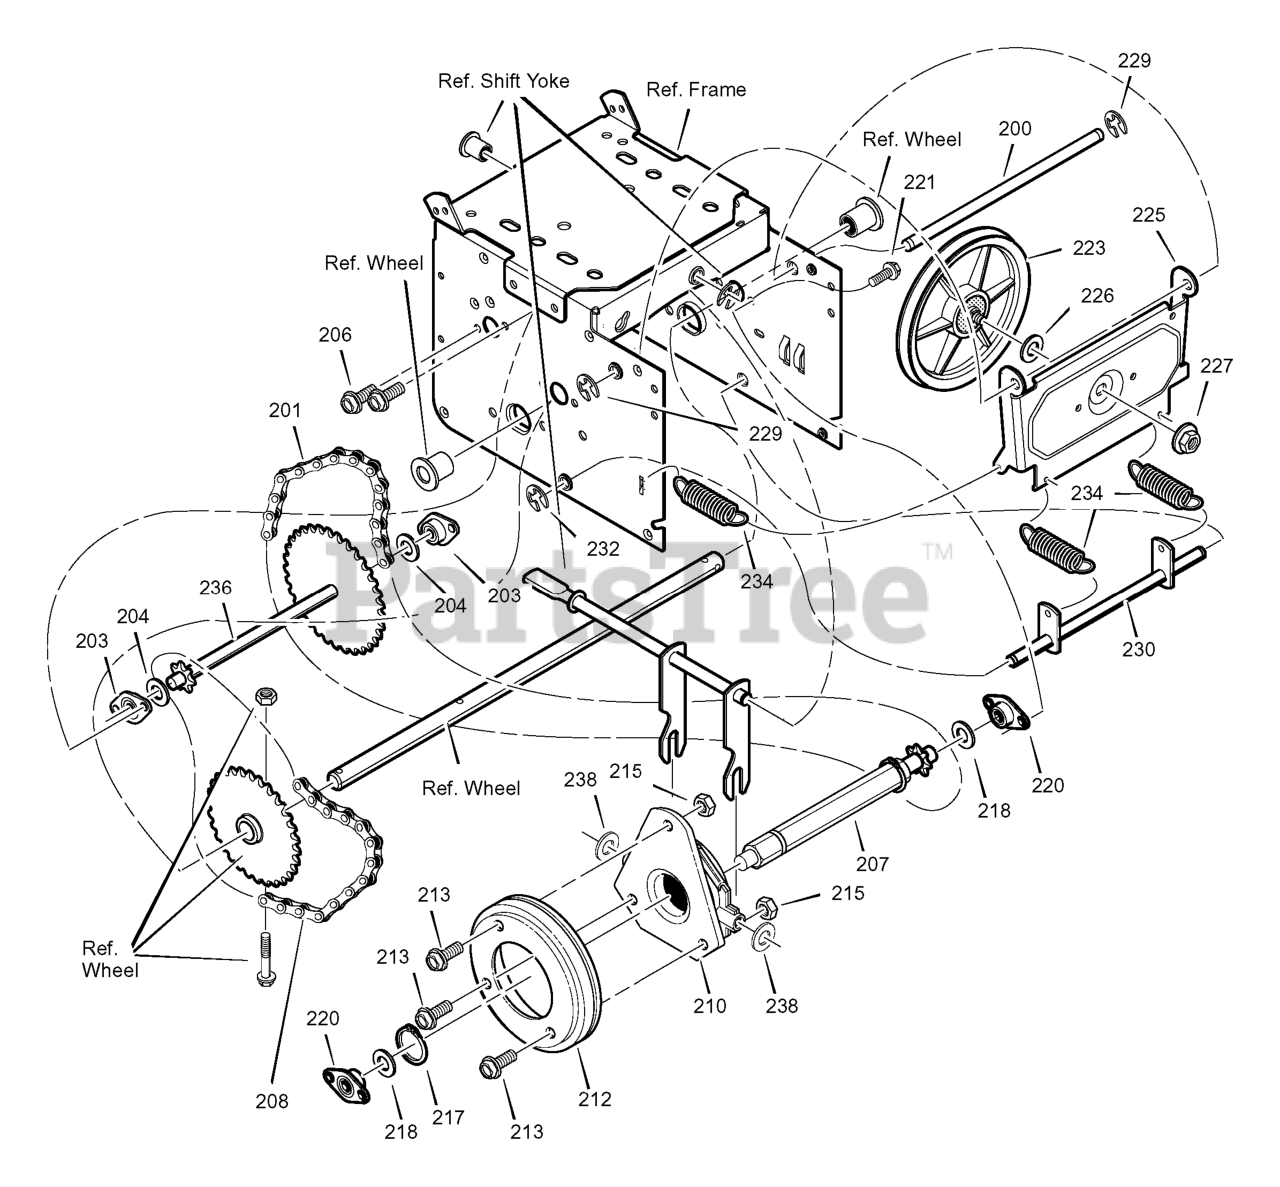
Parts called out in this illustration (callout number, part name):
200	LF AXLE, SWING PLATE YZ
201	CHAIN, ROLLER 19.00 LG
203	BEARING AND RETAINER, ASSY
206	SCREW, TAP 5/16-18 x 0.5
207	ASSY, HEX SHAFT
208	CHAIN, ROLLER 18.00 LG
210	BEARING, TRUNION CLUTCH R
212	WHEEL, FRICTION DISC
213	SCREW, 1/4-20 x 0.63
215	NUT, KEPS HEX 1/4-20
217	RING, RETEXT
220	BEARING AND RETAINER, ASSY
221	SCREW, TAP 5/16-18 X .50
223	ASSY, FRICTION PULLY
225	LF PLATE, SWINGING YZ
226	SPACER, FRICTION PULLEY
227	NUT, FLANGE LOCK 3/8-24
229	RETAINER, RING
230	LF ASSY, SPRING LINK YZ
232	RETAINER, RING
234	SPRING, EXTENSION
236	WLD, INTERMED SPROCKET 33T/7
238	WASHER, FLAT
